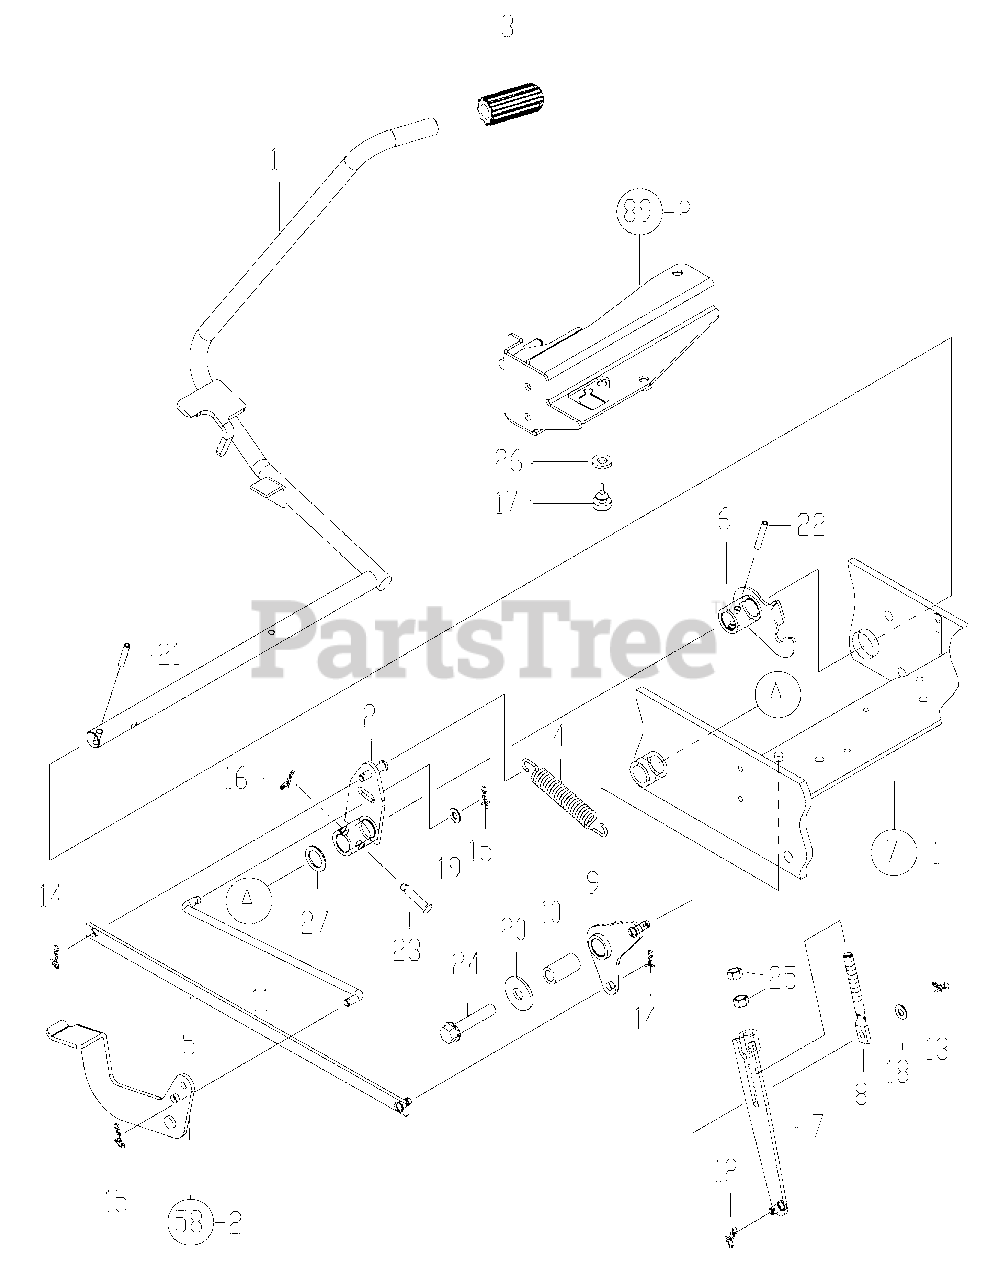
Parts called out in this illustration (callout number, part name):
1	PEDAL CMP, BRAKE
2	ARM CMP, BRAKE
3	HEAD, BRAKE PEDAL
4	SPRING, RETURN
6	ARM,RELEASE CMP
9	ARM CMP,BRAKE REAR
17	STOPPER, PEDAL
21	PIN, 6.0A X 32
22	PIN, 6.0A X 40
27	WASHER, 20 X 30 X 2
